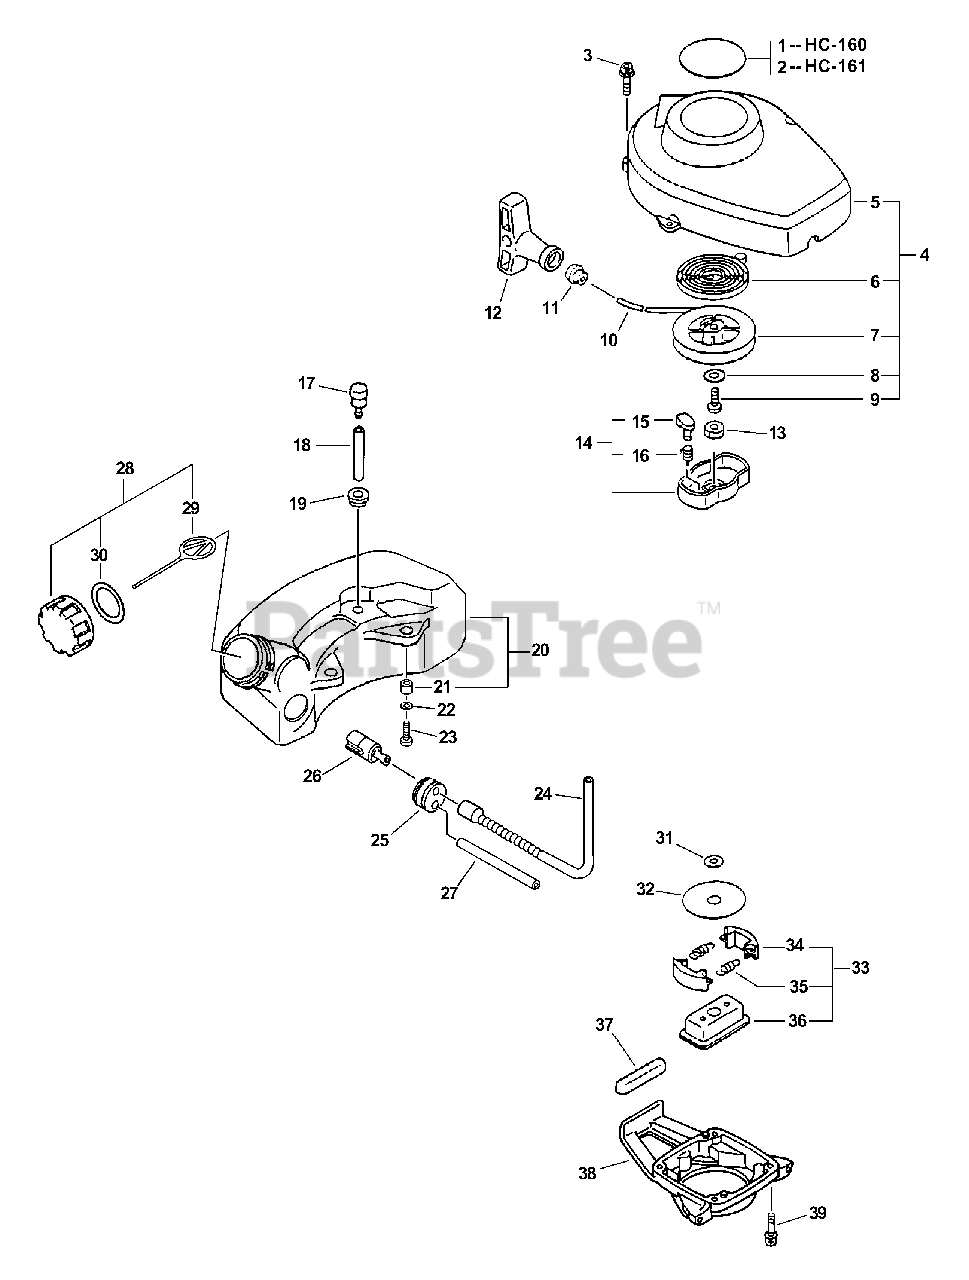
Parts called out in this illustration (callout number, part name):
1	LABEL, MODEL
2	LABEL, MODEL
3	BOLT 4×16
4	STARTER ASSY
5	CASE, STARTER
6	SPRING, RECOIL
7	REEL, ROPE
8	WASHER
9	SCREW
10	ROPE, STARTER
11	GUIDE, ROPE
12	GRIP, STARTER
14	PAWL ASSY, STARTER
15	PAWL, STARTER - BLACK
16	SPRING, RETURN
17	VENT ASSY
18	PIPE, FUEL
19	GROMMET
20	TANK, FUEL
21	SPACER 6.2×7.8×6
22	WASHER 5.5×12×0.8
23	SCREW 5×16
24	PIPE, FUEL
25	GROMMET, FUEL
26	FILTER, FUEL
27	PIPE, FUEL RETURN 3×6×110
28	CAP ASSY, FUEL
29	CONNECTOR, CAP L= 100 MM
30	GASKET, FUEL CAP
31	WASHER, CLUTCH
32	PLATE, CLUTCH
33	CLUTCH ASSY
34	SHOE, CLUTCH
35	SPRING, CLUTCH
36	HUB, CLUTCH
37	CUSHION, FUEL TANK
38	HOUSING, CLUTCH
39	BOLT 4×16
